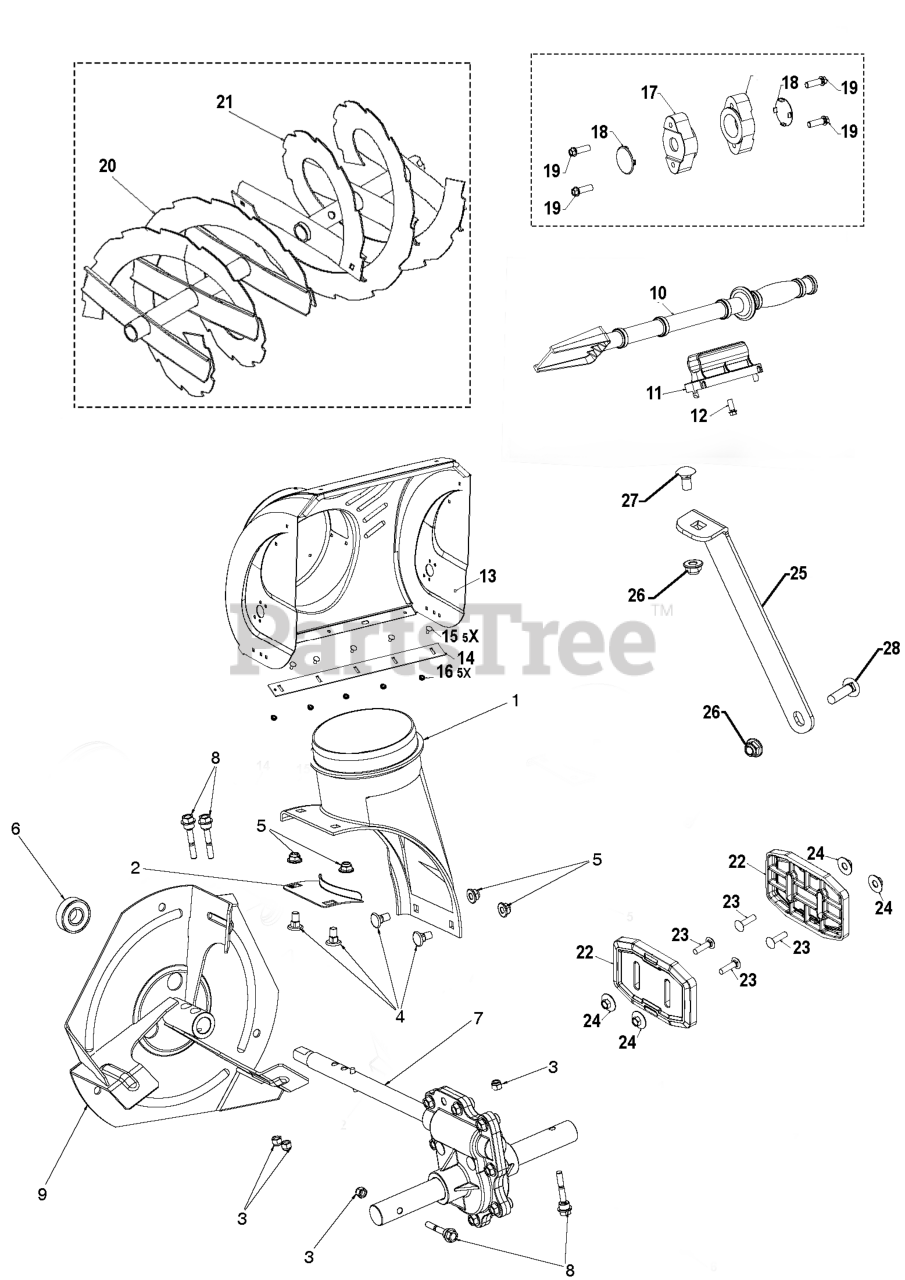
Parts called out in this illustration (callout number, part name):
1	CHUTE.DISCHARGE.BASE
3	NUT HEXAGON 1/4-20 ST ZPB
4	BOLT CARR WAFER BLK 5_16-18 X
5	NUT HEX FLG NYLOCK BLK 5_16-1
8	BOLT SHEAR HX HD 1/4-20 CLEAR
9	IMPELLER.STEEL.SNOW.BLACK
10	CLEAN OUT TOOL
11	CLIP.CLEANOUT.TOOL
12	SCREW.HWH.13-16-5.8.BZP
13	KIT.AUGER.HOUSING.586184005
14	BAR.SCRAPER.27.PNT.BLACK
15	BOLT ROUND HEAD SQUARE NECK BO
16	GSPW Hardware
17	BEARING.AUGER.SHAFT
18	PLUG.BEARING.HOLE.HSG
19	SCREW.HI-LO. 5/16 X 1.00
20	AUGER.WELD.RIB.BUT.27.LH.GREY
20	AUGER WELD RIB BUT LH PNT 420
21	AUGER.WELD.RIB.BUT.27.RH.GREY
21	AUGER WELD RIB BUT RH 27 PNT
22	PLATE.SKID.SHOE.COMPOSITE
23	BOLT CAR BLK 5/16-18 X 1-1/4
24	NUT.CENTERLOCK.5/16-
25	BRACE SUPPORT GEARBOX 200 SERI
26	NUT HEX FLG NYLOCK BLK 5_16-1
27	BOLT CAR BLK 5/16-18 X 5/8
28	BOLT.CARRIAGE.5/16-18
